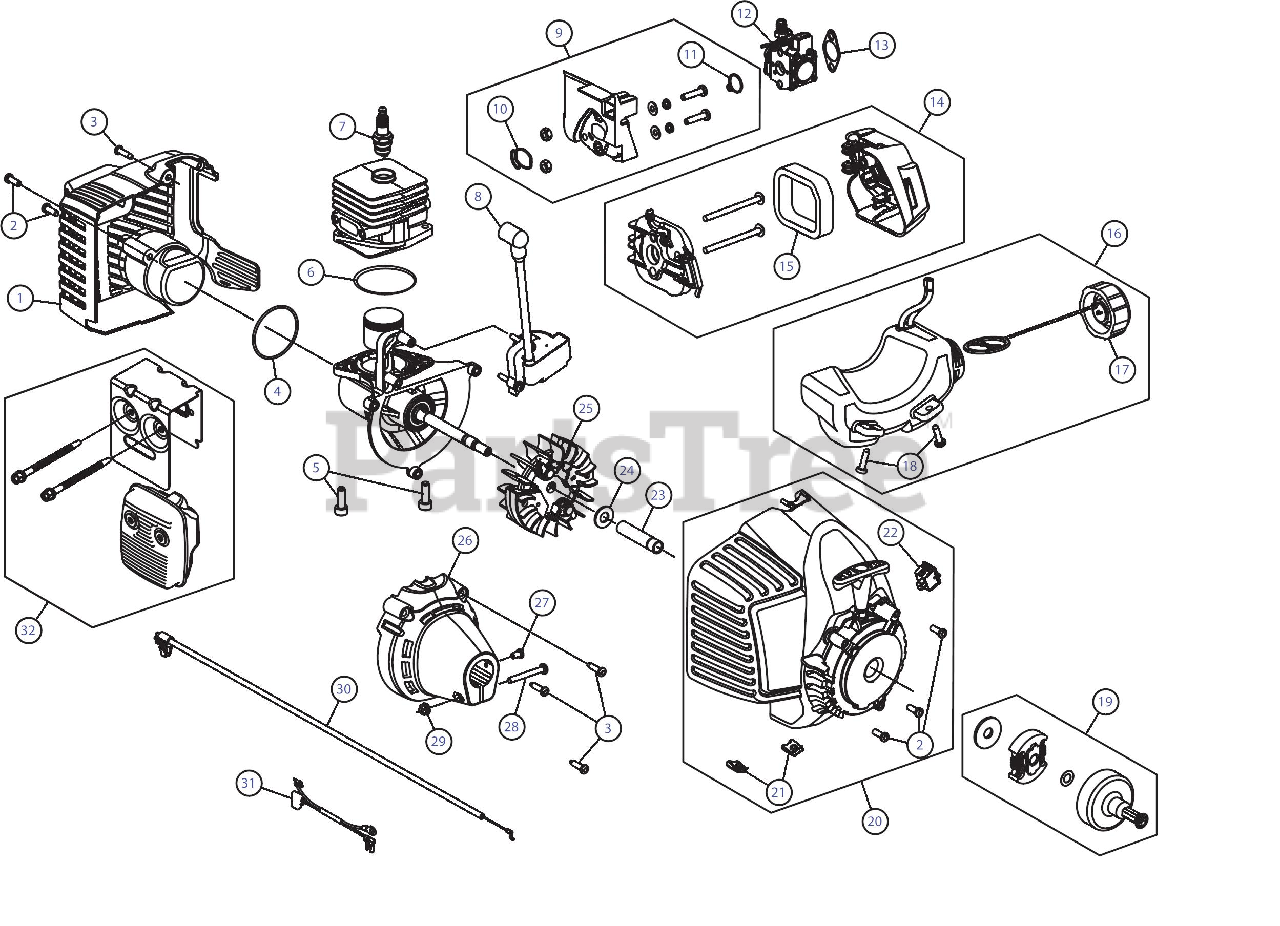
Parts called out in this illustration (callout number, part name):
1	Rear Cover Assembly (Incl. 2 & 3)
2	Housing Screw
3	Cover Screw
4	O-Ring
5	Crankcase Bolt
6	Crankcase O-Ring
7	Spark Plug
8	Module Assembly
9	Insulator Assembly (Incl. 10 & 11)
10	Insulator O-Ring
11	Carburetor O-Ring
12	Carburetor
13	Air Cleaner Gasket
14	Air Cleaner Cover Assembly (Incl. 15)
15	Air Cleaner Filter
16	Fuel Tank Assembly (Incl. 17 & 18)
17	Fuel Tank Cap
18	Fuel Tank Screw
19	Starter Clutch Assembly
20	Starter Housing (Incl. 2, 21 & 22)
21	U-shaped Nut
22	Switch Assembly
23	Spacer
24	Washer
25	Flywheel Assembly
26	Clutch Cover (Incl. 3)
27	Anti-rotation Screw
28	Clamp Screw
29	Clamp Nut
30	Throttle Cable
31	Lead Wires
32	Muffler Assembly
